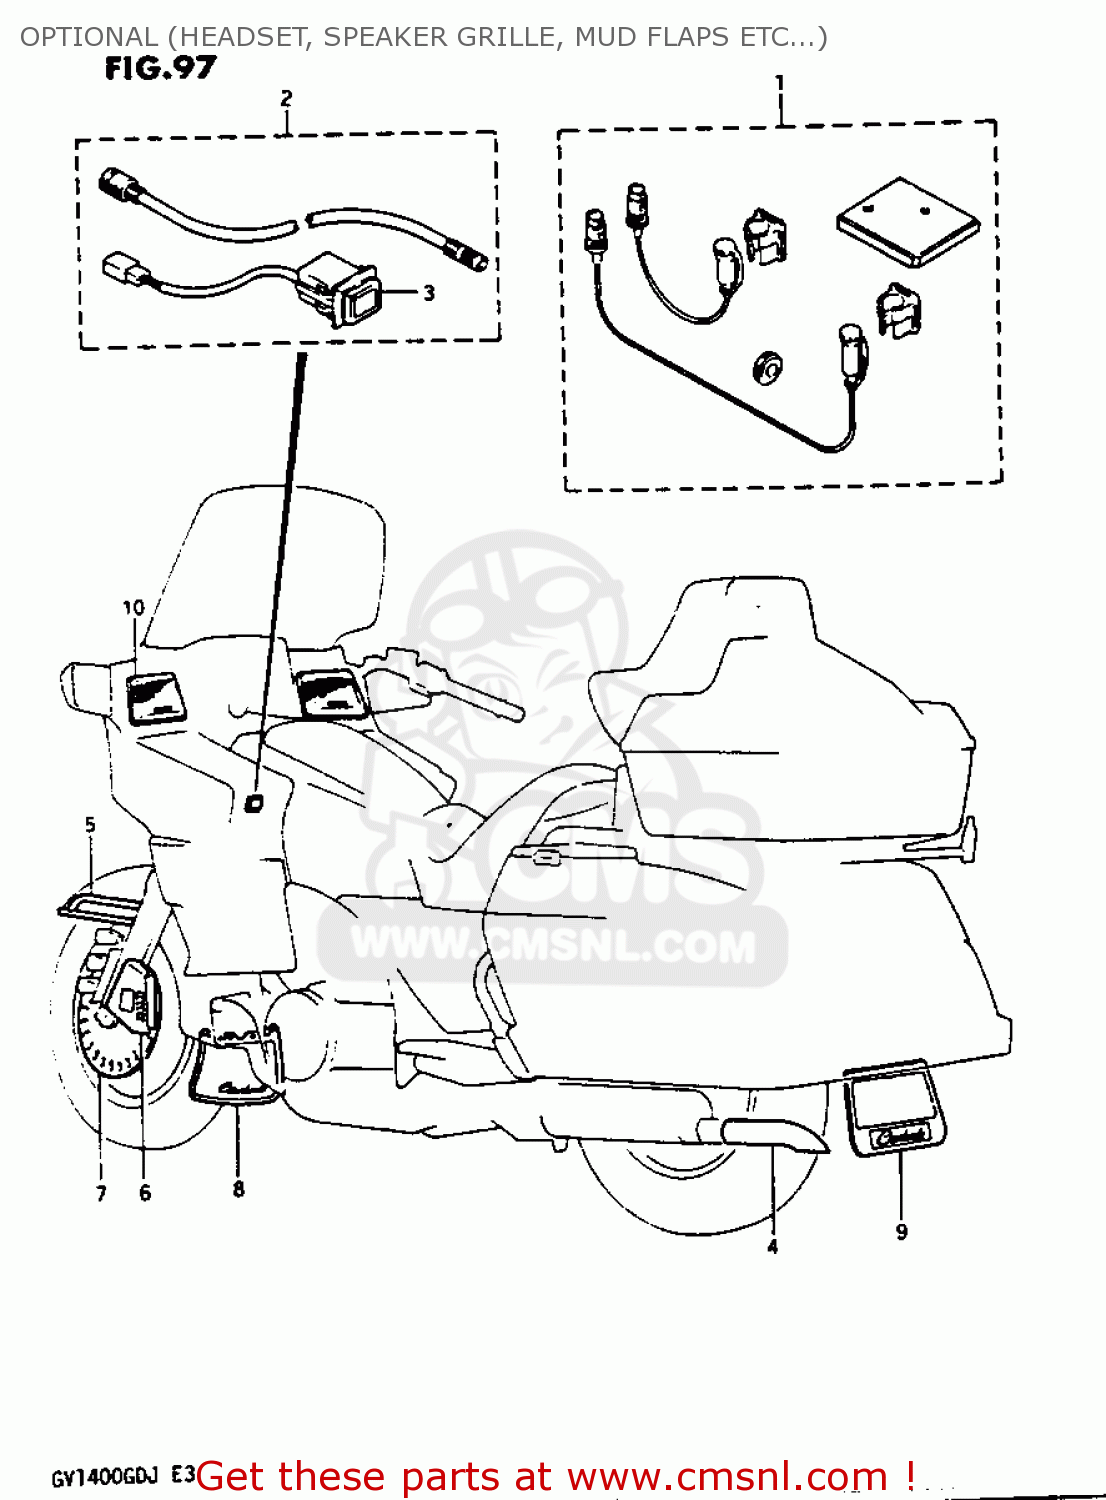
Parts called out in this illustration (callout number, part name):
1	HEAD SET,JUNCTION LEAD
2	AUXILIARY AIR HOSE SET
3	SWITCH ASSEMBLY,AIR AUXILIARY
4	EXHAUST EXTENSION
5	FRONT FENDER TRIM
6	FRONT CALIPER COVER SET
7	COVER,FRONT DISC,RIGHT
8	GUARD,MUFFLER,FRONT
9	MUD GUARD,REAR FENDER
10	GRILLE SET,SPEAKER
